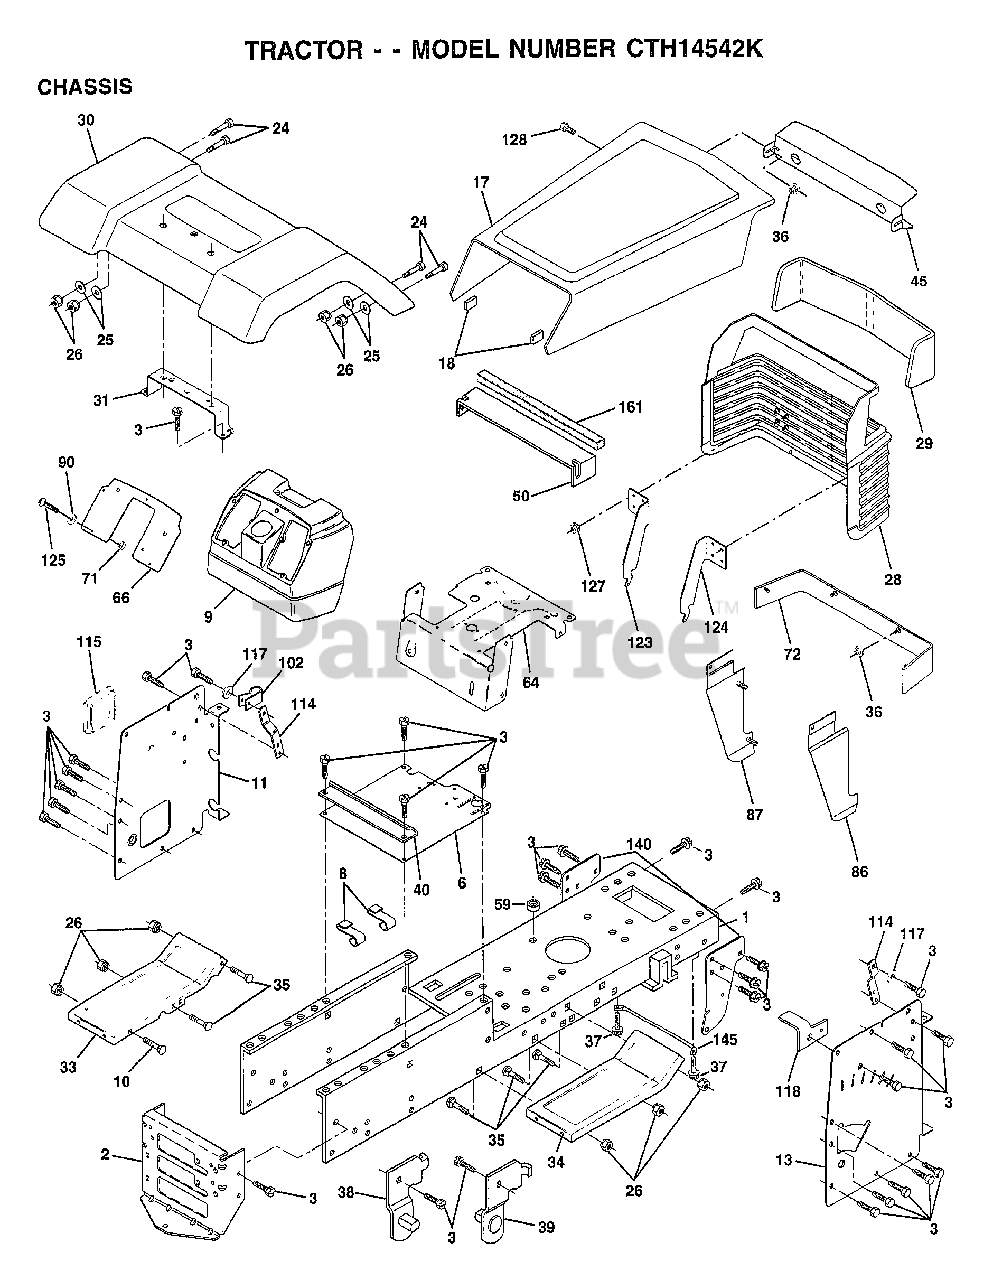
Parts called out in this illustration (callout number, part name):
1	CHASSIS.STAMPING
3	SCREW
6	SADDLE
8	"CLIP,INSULATOR"
9	DASH.PLASTIC.BLK
11	PANEL.DASH.LH.
13	PANEL.DASH.RH.
17	HOOD/GRILLE ASM
24	BOLT
25	WASHER
26	NUT
28	GRILLE ASM WELD
30	FENDER.LTST.WLDMNT.W.SHIFT
31	BRACKET SUPT FEND
33	FOOTREST.LH.LT/GT
34	FOOTREST.RH.LT/GT
35	BOLT
36	PAL NUT LT
37	SCREW LT
38	BRACKET ASM LH
39	BRACKET ASM RH
40	SPACER FENDER LT
45	BEZEL.LIGHT.SLVR
50	"BAFFLE,HOOD"
64	DASH.LOWER.LT
72	STRAP FENDER ASM
86	PANEL SIDE RH ASM
87	PANEL SIDE LH ASM
90	WASHER PM
102	CLIP T
114	BRACKET.SUPT.DASH
115	COVER ACCESS
117	WASHER.SERRATED.
118	BRACKET.CLUTCH.MC
123	BRACKET.PICK.LH.
124	BRACKET.PICK.RH.
125	SCREW
127	PAL NUT
128	SCREW SPECIAL
140	BRKT SUSPENSION
145	"ROD POVOT,CHASSIS"
161	EXTRUSION HOOD
